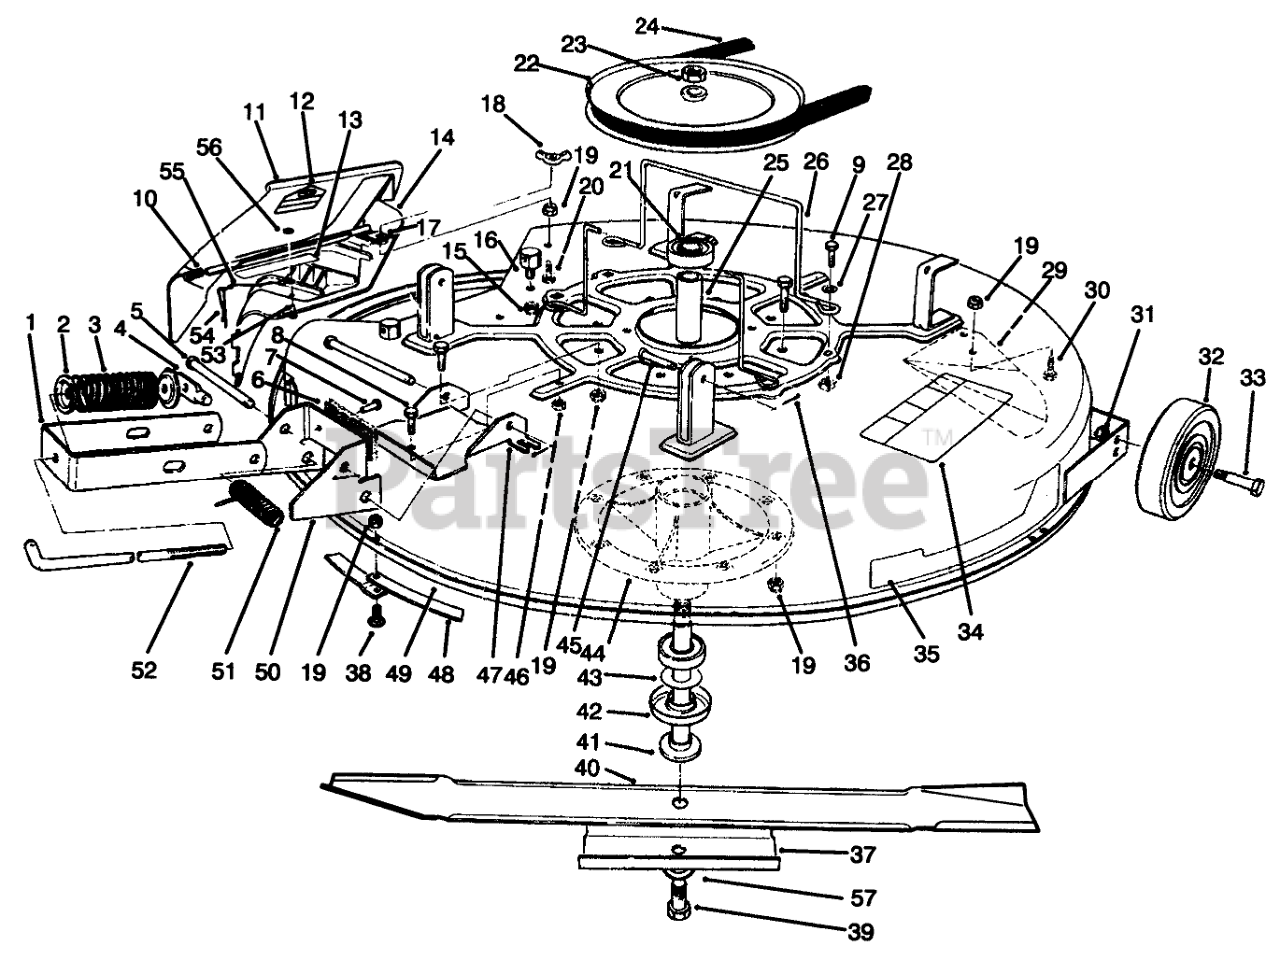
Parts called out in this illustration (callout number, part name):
1	Bracket-Engagement
2	RETAINER-SPR. TOP
3	SPRING-COMPRESSION
4	SHAFT-DECK ADJ.
5	PIN-CLEVIS
6	PAD-BRAKE
7	RIVET-BLIND
8	SCREW-HH
9	SCREW-HH
10	SPRING
11	Assembly-Deflector (Incl. Ref. #12)
12	DECAL-DANGER
13	DECAL-DANGER, DEFLECTOR
14	Assy.-Cover, Discharge (Incl. Ref. #53-56)
15	NUT-LOCK, NI
16	POST-PIVOT
17	Brace-Cover, Rear
18	NUT-WING
19	NUT-LOCK, NI
20	SCREW-HH
21	BEARING-BALL
22	PULLEY
23	NUT-HEX
24	V-BELT, DECK
25	SPACER-BEARING
26	GUIDE-BELT
27	WASHER-PLAIN
28	NUT-RETAINER
29	Kicker
30	SCREW-HH
31	NUT-LOCK, NI
32	WHEEL-DECK
33	BOLT-WHEEL
34	DECAL-DANGER, THROWN OBJECT
35	DECAL - RECYCLER 32"
36	PIN-COTTER
37	STIFFENER
38	SCREW-PPH
39	SCREW-HH
40	BLADE-RECYCLER
41	SHAFT-SPINDLE
42	SHIELD-BEARING
43	SPACER-HARDNED
44	SPINDLE
45	PIN-CLEVIS
46	NUT-HEX
47	Plate-Deck, Brake Mtg.
48	RING-DECK
49	Deck-Cutting
50	Assembly-Brake (Incl. Ref. #6-7)
51	SPRING
52	ROD-ENGAGEMENT
53	RIVET-BLIND
54	PIN-LOCKING, CHUTE
55	LANYARD
56	WASHER-PLAIN
57	WASHER-BELLEVILLE
